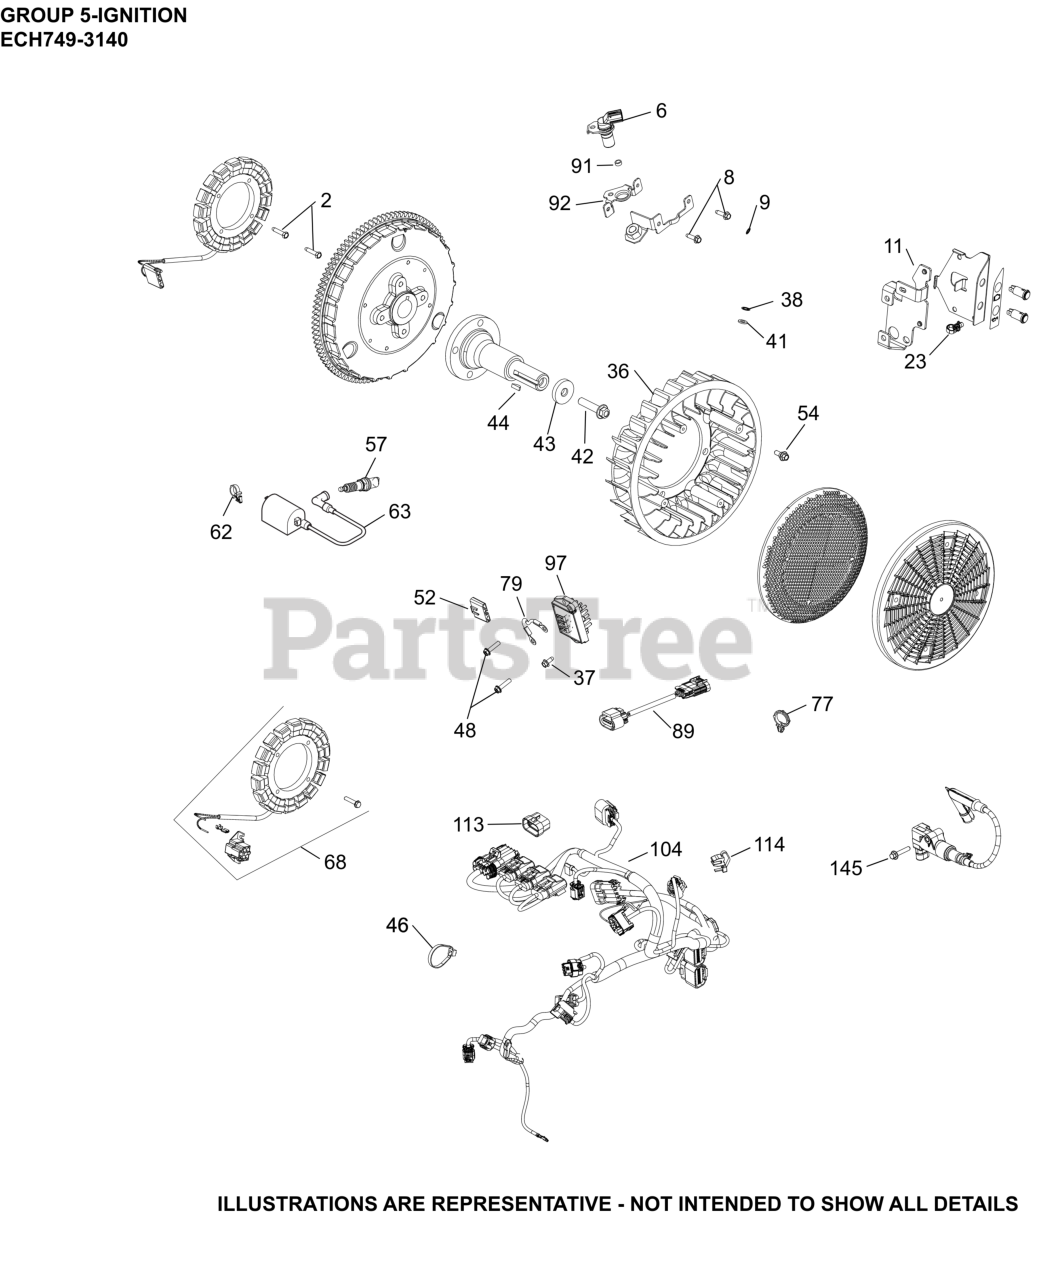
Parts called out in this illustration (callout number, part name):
2	SCREW, THREAD FORMING
6	SENSOR, SPEED
8	SCREW, THREAD FORMING
9	WASHER, INT TOOTH LOCK #10
11	BRACKET, ECU
23	TIE, WIRE
36	FAN-USE 24 755 253-S
37	SCREW, THREAD FORMING
38	WASHER, INT TOOTH LOCK 1/4"
41	WASHER, FLAT 1/4" (O.D. 1/2")
42	SCREW, HEX FLANGE
43	WASHER, FLAT
44	KEY, 3/16" X 5/8"
48	SCREW, HEX FLANGE HI-LO
52	CONNECTOR
54	BOLT, SHOULDER
57	PLUG, SPARK (STD)
63	COIL, IGNITION - EFI
68	KIT, 25 AMP STATOR ASSY.
77	RETAINER, WIRE HARNESS
89	HARNESS, WIRING ASSEMBLY
92	BRACKET, SENSOR
97	REGULATOR, RECTIFIER (20-30AMP,FW W/OVP)
104	HARNESS, WIRING (B-BAY, EFI-ETB)
113	CAP, DIAGNOSTIC (8-WAY)
114	TIE, WIRE EDGE FIXED
145	SCREW, HEX FLANGE
NI	FLYWHEEL, ASSEMBLY
NI	MODULE, SPEED ADVANCE -USE 24 584 34-S
